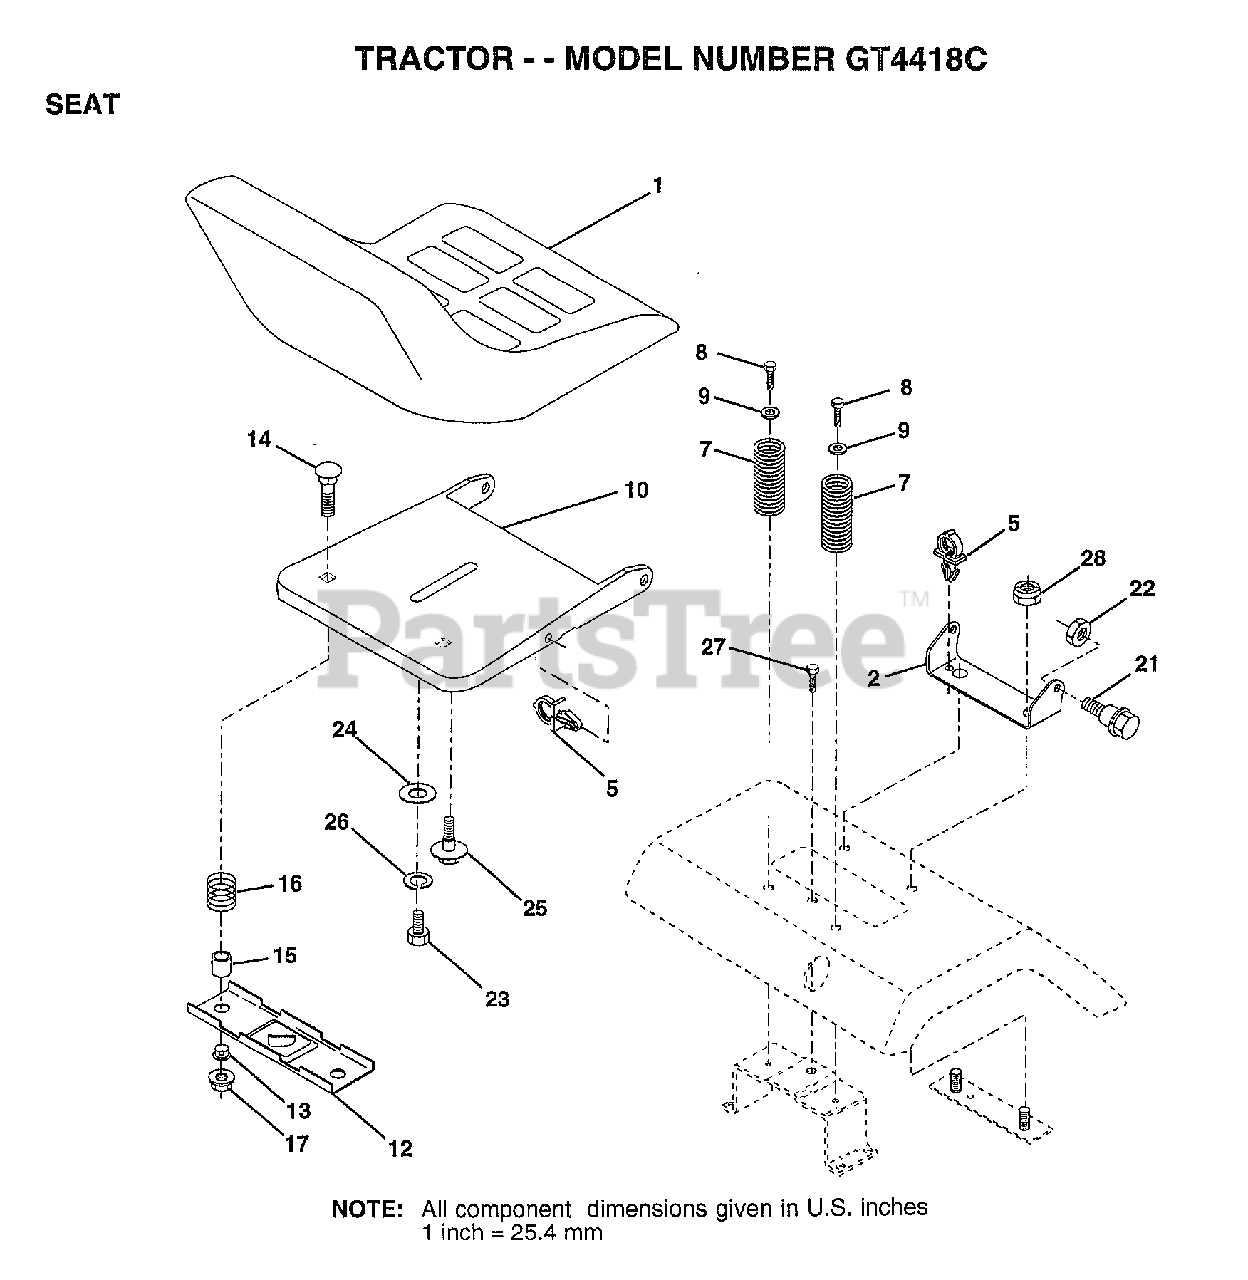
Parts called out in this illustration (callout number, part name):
2	BRACKET PVT SEAT
5	CLIP.PUSH-IN.HING
7	SPRING COMPRESSIO
8	SCREW LT
9	WASHER
12	BRKT SWITCH
13	BUSHING
15	SPACER SPLIT
16	SPRING COMPRESSED
21	BOLT.SHLD.5/16-18
23	BOLT
24	WASHER
25	"BOLT,SHOULDER"
26	LOCKWASHER
27	SCREW LT
